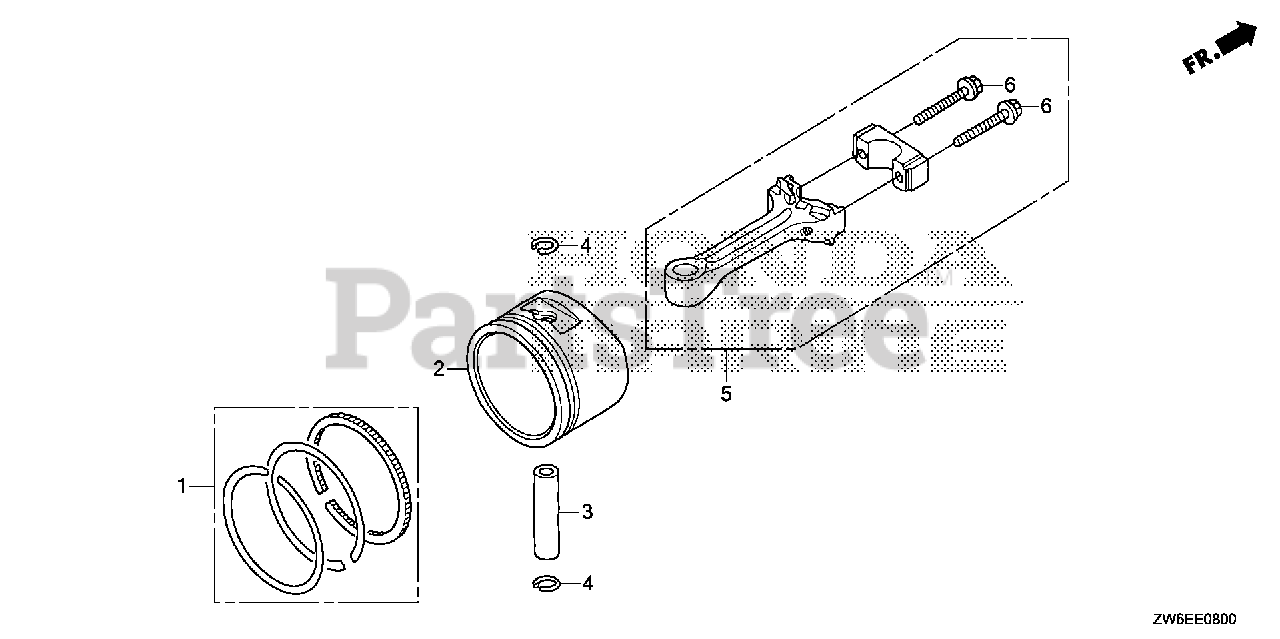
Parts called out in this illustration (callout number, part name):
1	RING SET, PISTON (STD)
2	PISTON (STD)
3	PIN, PISTON
4	CLIP, PISTON PIN (10MM)
5	ROD ASSY., CONNECTING
6	BOLT, CONNECTING ROD
